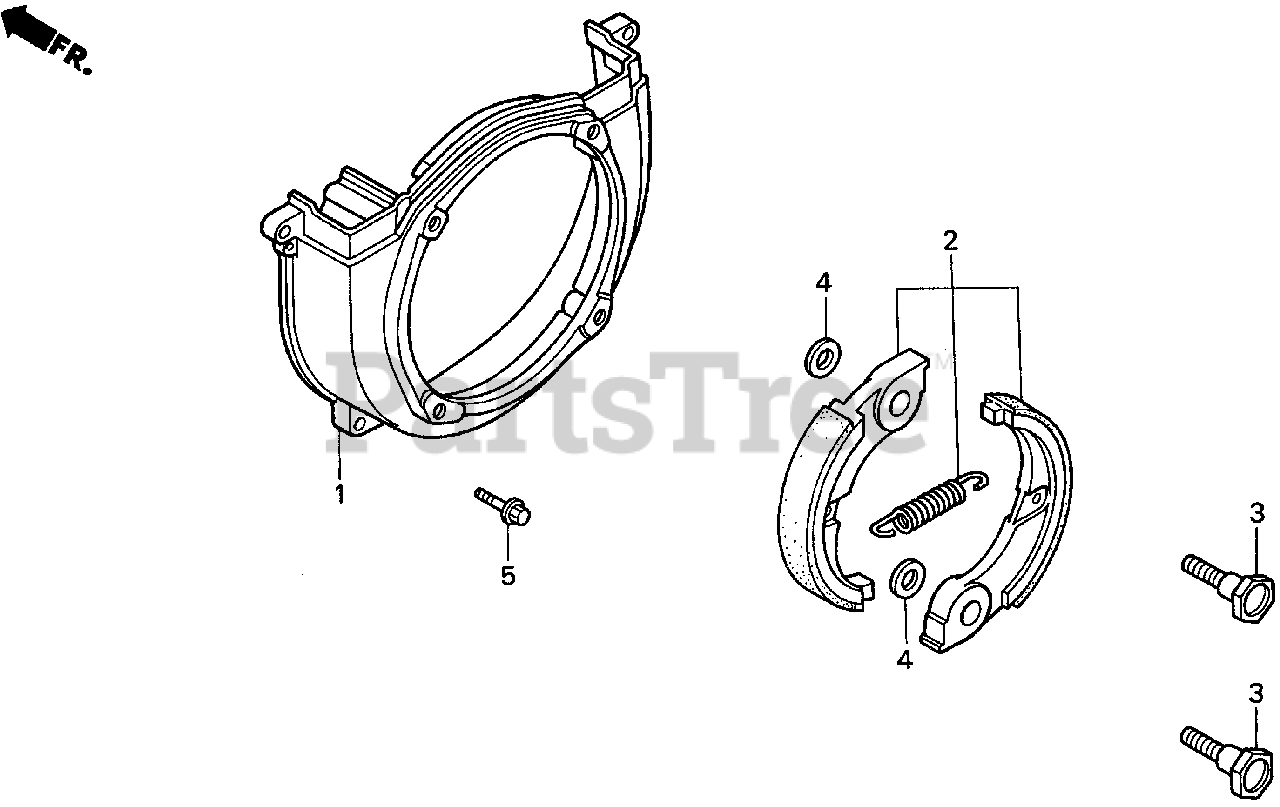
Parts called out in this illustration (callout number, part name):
1	COVER, FAN
2	CLUTCH ASSY.
3	BOLT, CLUTCH (8MM)
4	WASHER, CLUTCH (8X17)
5	BOLT, FLANGE (5X18)
